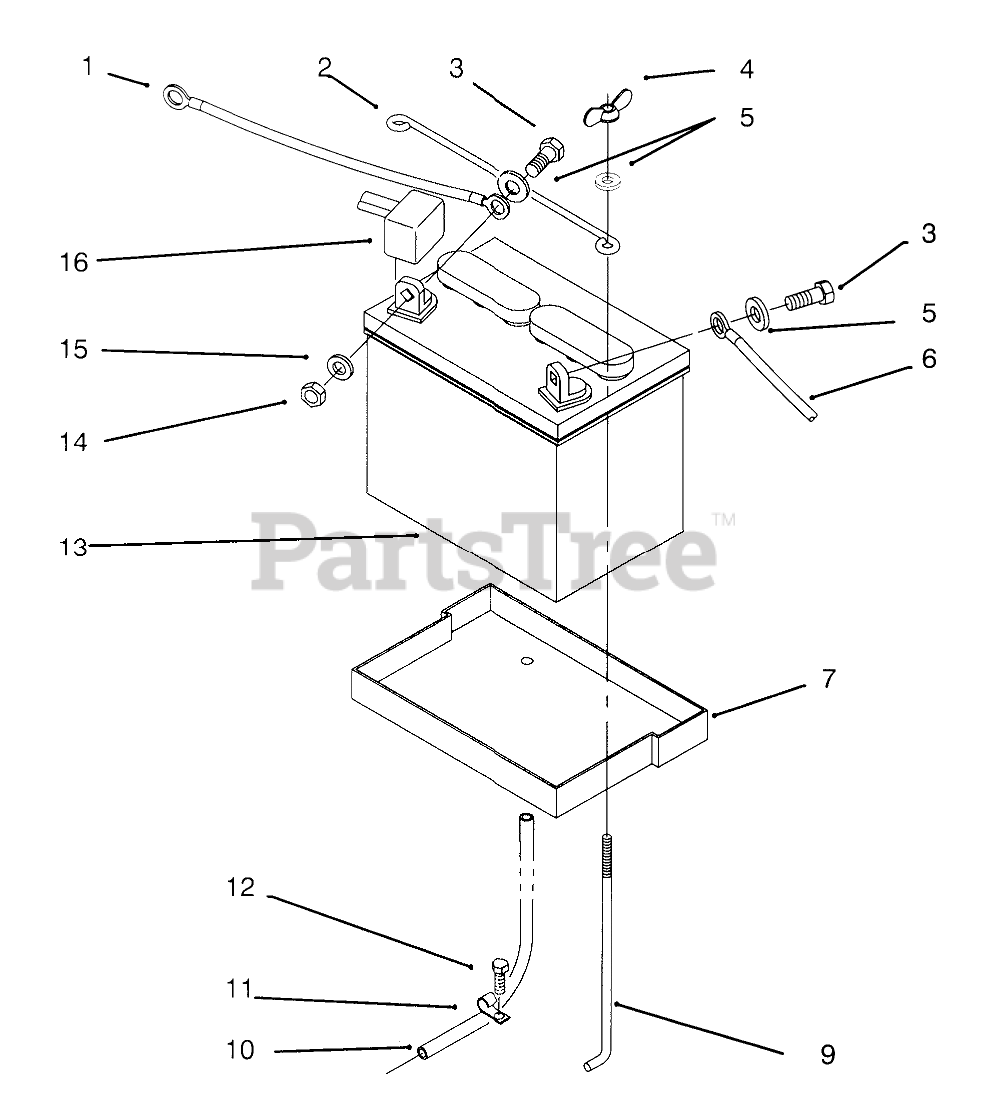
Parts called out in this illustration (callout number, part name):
1	CABLE-BLACK
2	HOLDDOWN-BATTERY
3	SCREW-HH
4	NUT-WING
5	WASHER-FLAT
6	ASSY WIRE
7	TRAY-BATTERY
9	HOOK-BATTERY RETAIN
10	TUBE-21" BATTERY DRAIN
11	CLIP
12	SCREW-HH
13	Battery
14	NUT-LOCK, NI
15	WASHER-LOCK
16	Boot
